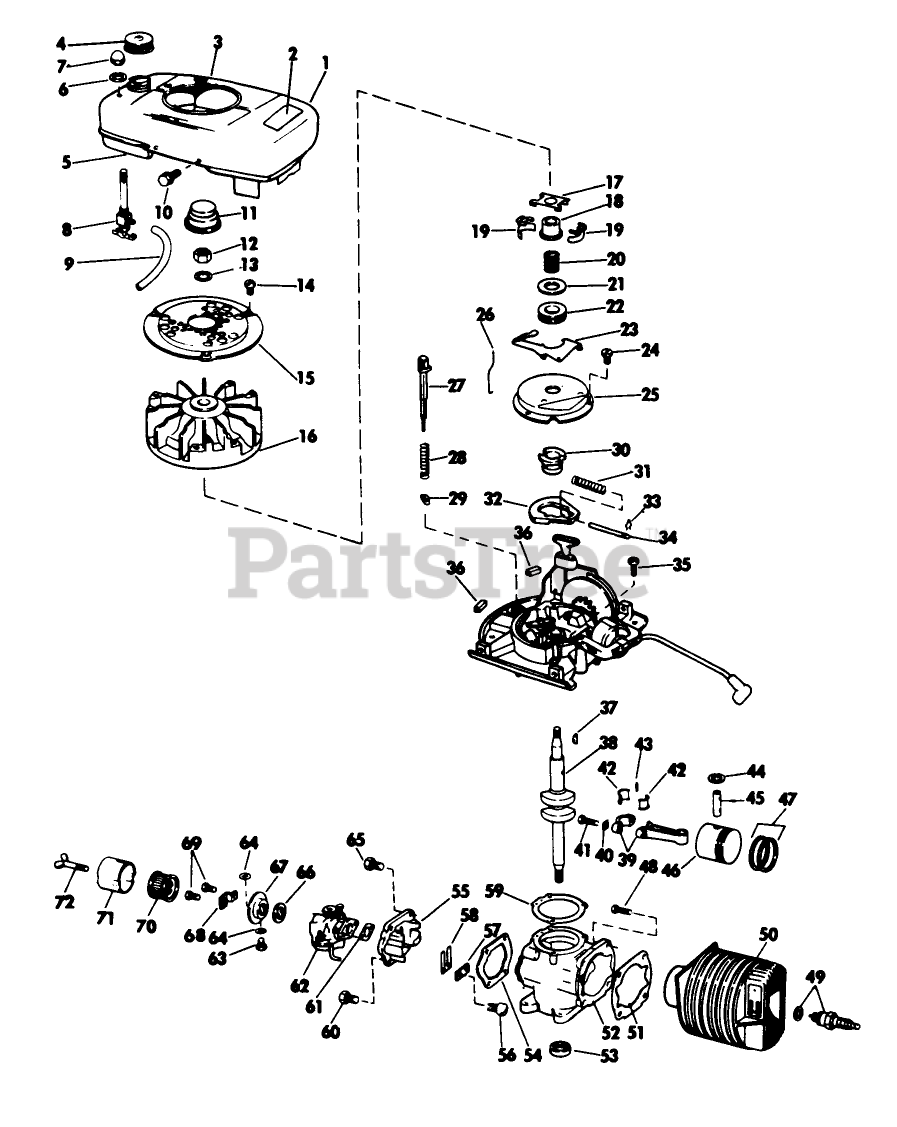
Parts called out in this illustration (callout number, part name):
7	PALNUT S
8	VALVE&SCREEN SM
10	SCREW S
15	Screen-Flywheel
18	COLLAR S
22	THRUST COLLAR S
23	LEVER-GOVERNOR S
24	SCREW S
25	DUST COVER S
28	SPRING S
30	SPARK ADV. S
31	SPARK ADV. SPRING S
32	FLYWEIGHT S
33	SPARK ADJ. SPRING
34	PIN,SPARK ADV. S
42	LINER ASM
44	RING-RETAINING
51	GASKET S
57	PLATE-BACKUP, REED
59	GASKET S
60	SCREW S
61	GASKET S
65	SCREW S
66	GASKET S
